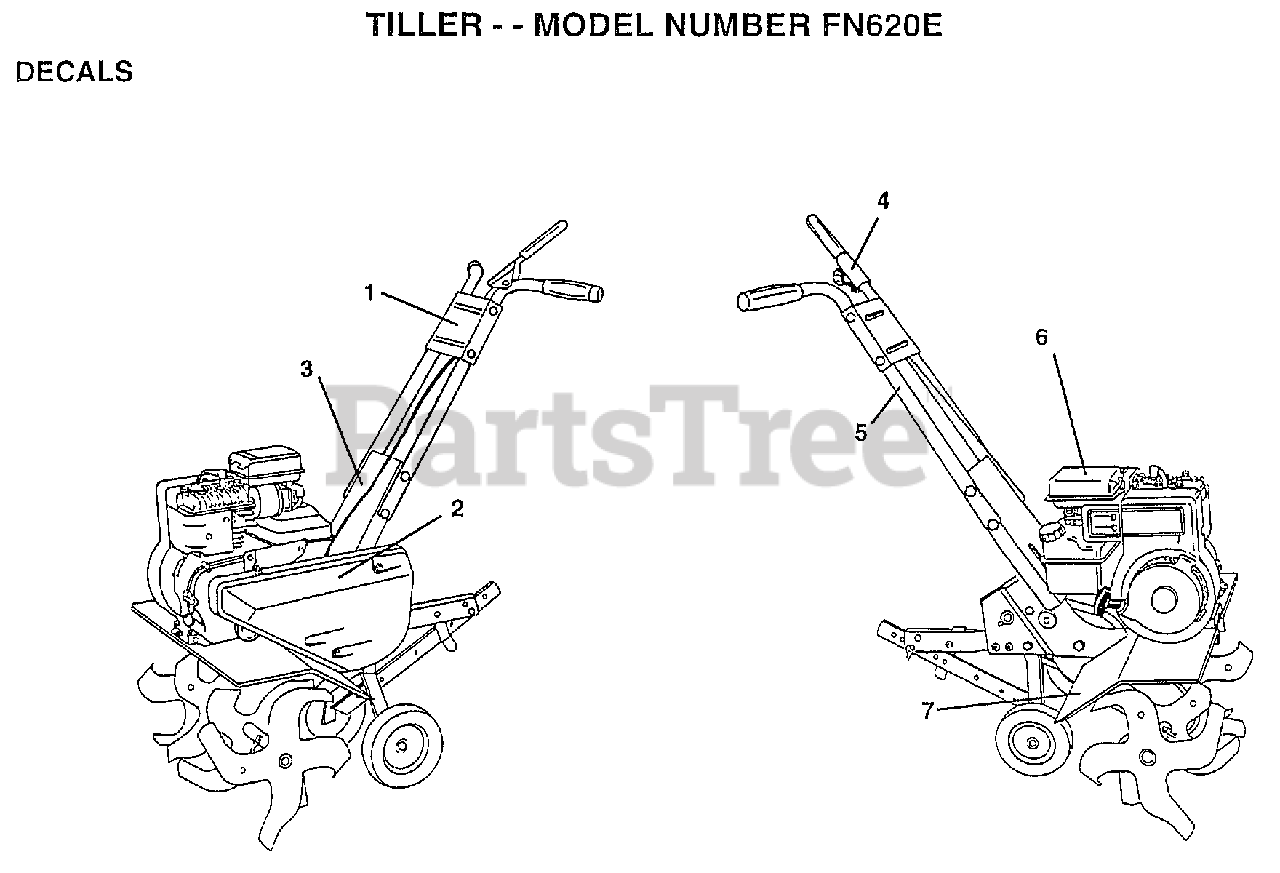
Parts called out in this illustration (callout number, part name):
1	DECAL HANDLE BRKT
4	DECAL TI
5	DECAL TI
6	DECAL TI
